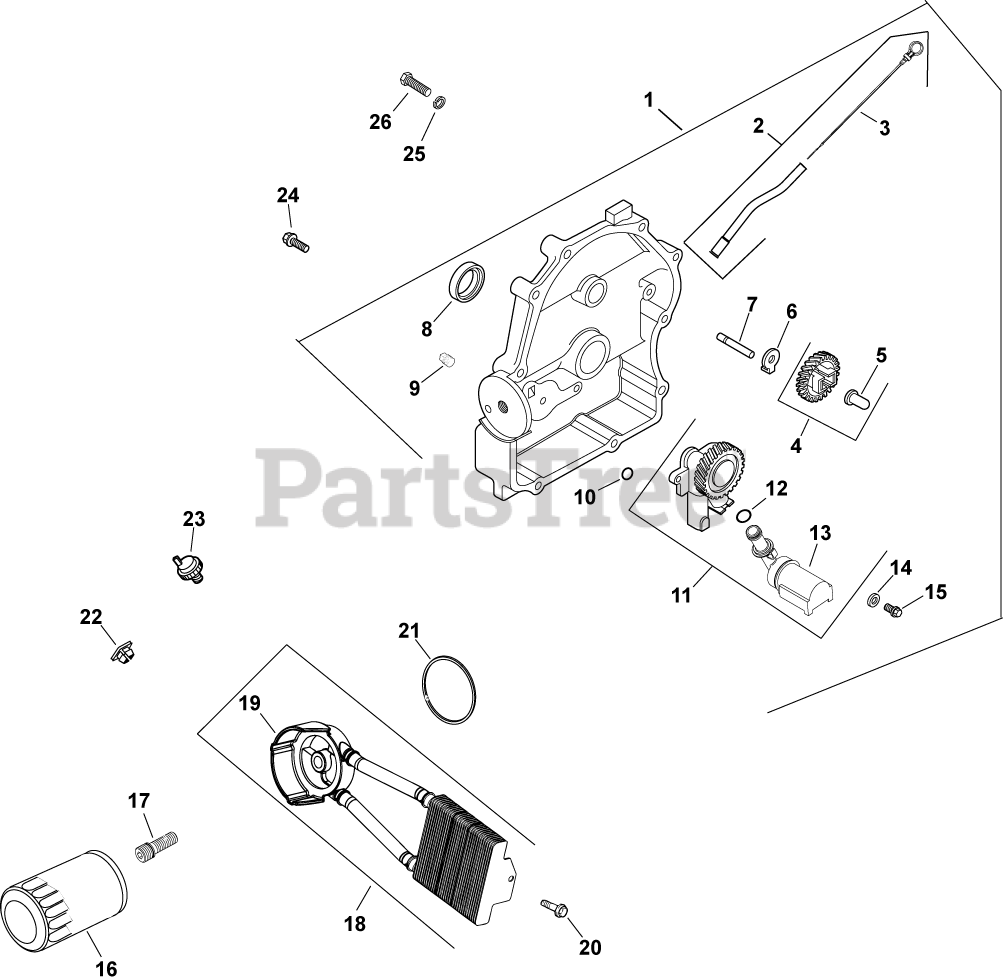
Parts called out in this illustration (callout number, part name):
2	KIT, DIPSTICK/DIPSTICK TUBES
4	KIT, GOVERNOR GEAR W/PIN
5	KIT, GOVERNOR GEAR W/PIN
6	TAB, LOCKING
7	SHAFT, GOVERNOR GEAR
8	SEAL, OIL
9	PLUG, CTSK PIPE 1/8"
11	PUMP ASSEMBLY, OIL-USE 24 393 53-S
12	O-RING, OIL PICK-UP
13	PICK-UP, OIL
14	WASHER, FLAT 6 MM
15	SCREW,FLG THD FRM M6X1.0X25-(#25086395S)
16	OIL FILTER
17	NIPPLE, OIL FILTER
18	COOLER, OIL - PHENOLIC-USE 24 594 36-S
19	ADAPTER, OIL FILTER-USE 24 029 75-S
20	SCREW, TAP M6X1.7X18
21	O-RING, OIL COOLER
22	NUT, PLASTIC - BLACK
23	SENSOR, OIL PSI
24	SCREW, FLG M8X1.25X45
25	WASHER, SPRING LOCK 7/16"
26	SCREW, CAP HD 7/16-14x2"
